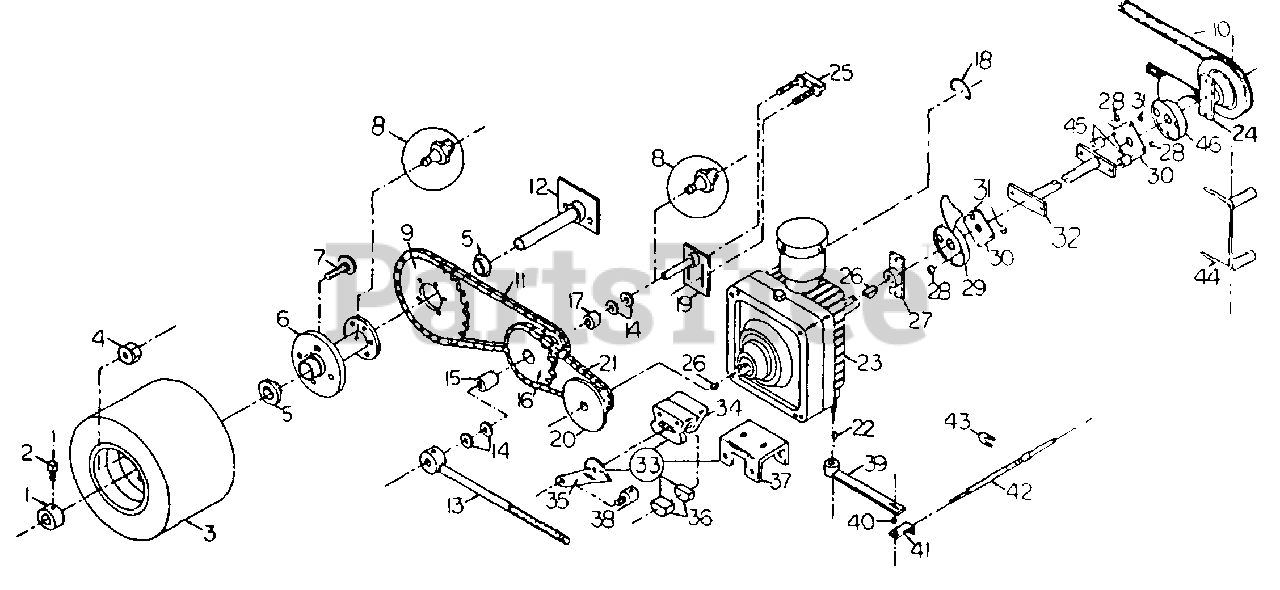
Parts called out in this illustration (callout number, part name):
1	Set Collar, 1"
2	Squarehead Setscrew, 5/16-18 x 1/2"
3	Drive Wheel Ass'y., 16 x 7.50-8
4	Lug Nut, 1/2-20
5	Drive Wheel Bearing
6	Drive Wheel Hub
6	Hub - Drive Wheel
7	Lug Bolt, 1/2-20 x 1 1/4"
8	Self-tapping Zerk, 1/4-28
9	Final Drive Sprocket, 40A 54
10	Transmission Belt
11	Final Drive Chain
11	Chain - Final Drive
12	Drive Wheel Axle
13	Support Collar
14	Machine Washer, 3/4", 10 GA
15	Idler Sprocket Bearing, 1/2"
16	Idler Sprocket
17	Idler Sprocket Bearing, 3/4"
18	Transmission Dump Valve Clip
19	Idler Sprocket Shaft
20	Transmission Sprocket w/Brake Disc
21	Chain - Primary Drive
21	Primary Drive Chain
22	Woodruff Key, 1/8" x 3/8"
23	Transmission, LH
24	Pulley w/Drive Plate
26	Woodruff Key, 1/8" x 1/2"
27	Hub w/Drive Plate
30	Drive Plate
31	Washer, 1/4", 10 GA
33	Brake Assembly, LH
34	Brake Caliper
35	Caliper Lever, LH
36	Brake Pad (Set)
37	Caliper Bracket
38	Caliper Rod Collar
39	Transmission Arm, LH
40	Cable End Bushing
41	Steering Cable End
42	Steering Cable
43	Steering Cable Clamp
44	Transmission Belt Retainer
